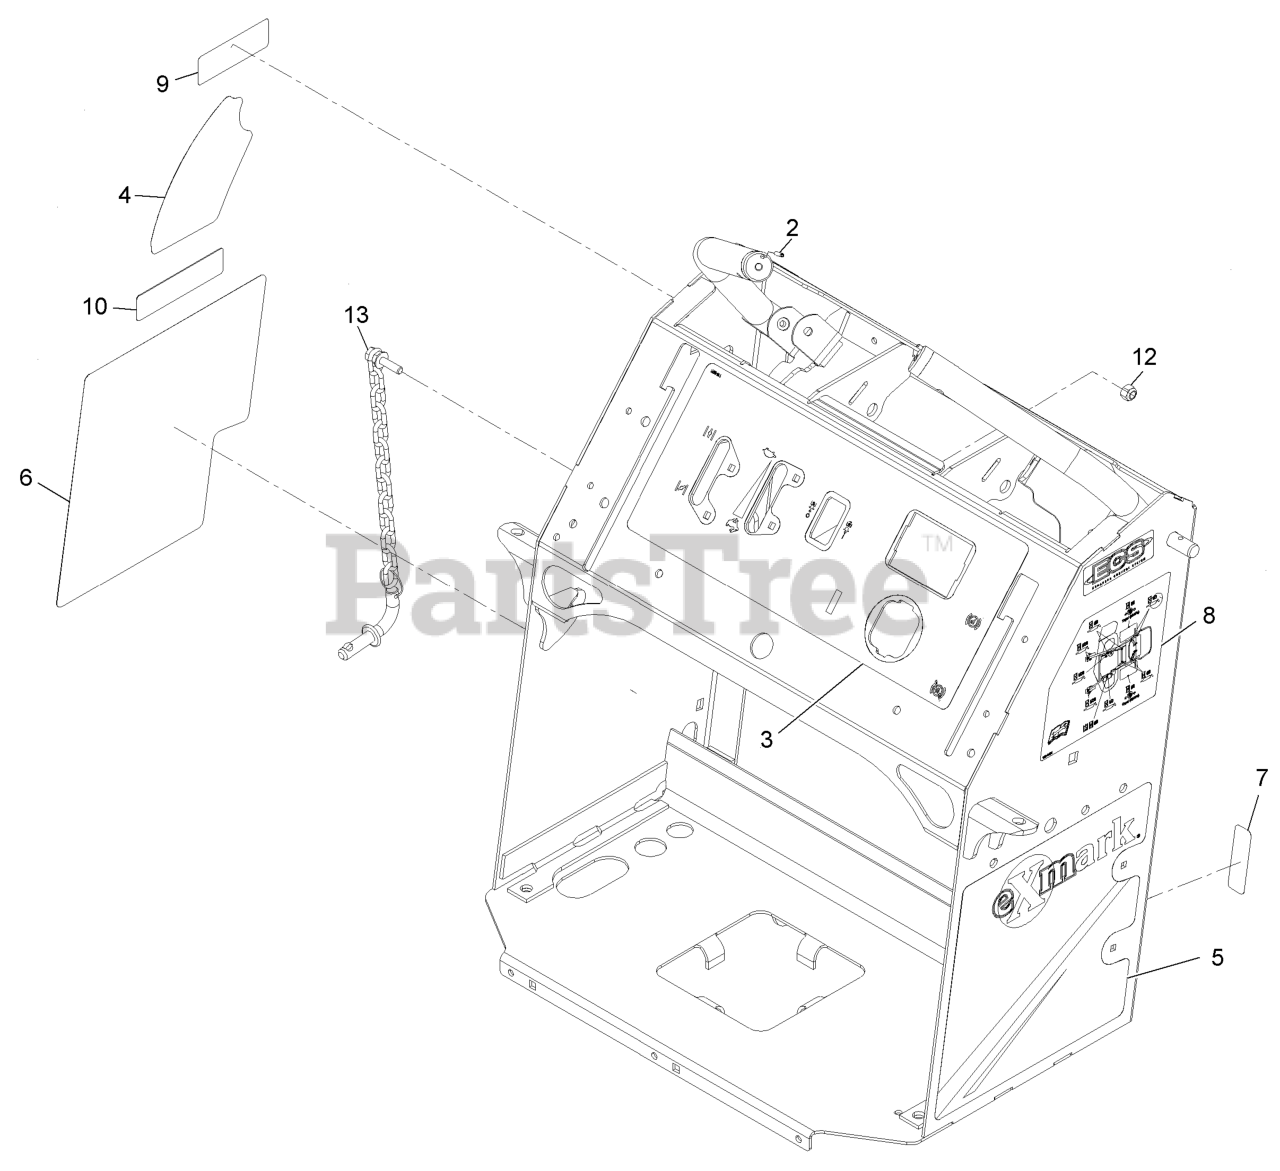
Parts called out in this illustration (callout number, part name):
2	PIN-SPRING
3	DECAL-CONTROL PANEL EFI
4	DECAL-HEIGHT OF CUT
5	DECAL-LH PANEL
6	DECAL-RH PANEL
7	DECAL-FUSE
8	Decal-Service Aid
9	DECAL-ECS LOGO
10	DECAL-ARRESTER, SPARK
12	NUT-LOCK, NI
13	HOC PIN ASM
